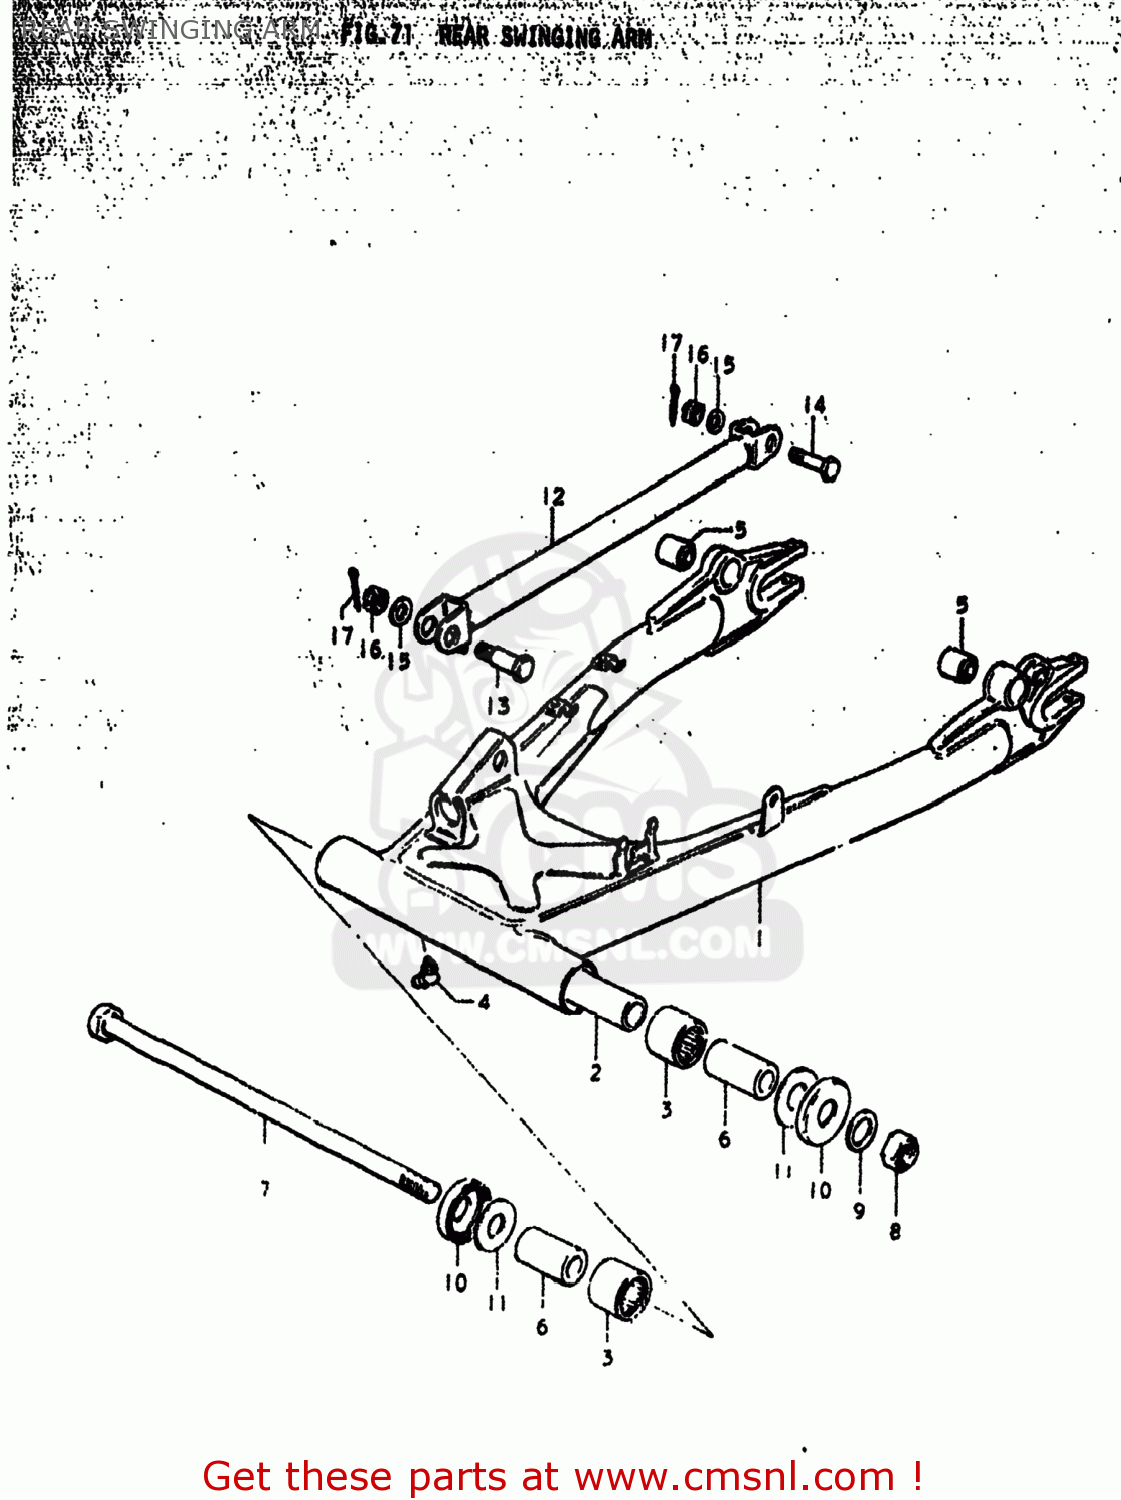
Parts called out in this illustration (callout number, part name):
1	SWING ARM ASSEMBLY,REAR
2	SPACER,SWING ARM,CENTER
3	BEARING(22X29X30)
4	NIPPLE,GREASE
5	BUSH
6	SPACER,RR SWGARM PIVOT
7	SHAFT,REAR SWING ARM
8	NUT 14MM
9	WASHER
10	COVER,REAR SWING ARM DUST
11	WASHER(14.2X34X1)
12	LINK,REAR TORQUE
13	BOLT
14	BOLT(10X39)
15	WASHER
16	NUT
17	PIN 20X20
